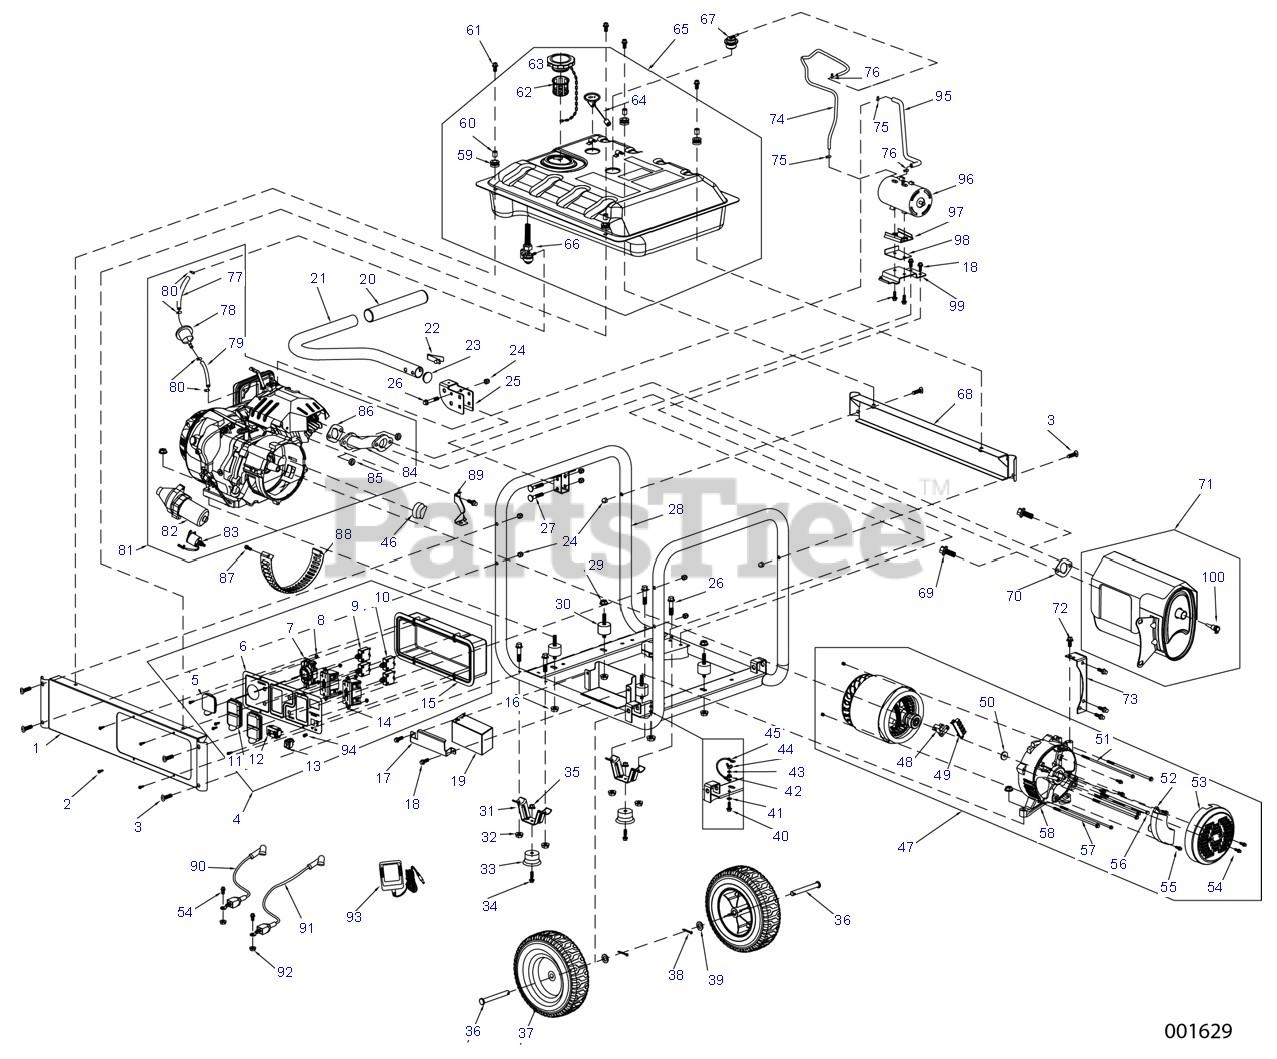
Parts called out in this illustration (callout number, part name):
1	FRAME RAIL
2	PAN SCREW (M5X16)
3	CURVED HEAD BOLT (M8X40)
4	CONTROL PANEL ASSEMBLY
5	OUTLET COVER
6	CONTROL PANEL FACE PLATE
7	OUTLET 30A 120/250V
9	30A CIRCUIT BREAKER
10	20A CIRCUIT BREAKER
11	OUTLET COVER
12	HOUR METER
13	ENGINE SWITCH
14	OUTLET 20A 120V GFCI
15	BACK PANEL COVER
17	BATTERY BRACKET COVER
18	BOLT(M6X12)
19	BATTERY
20	HANDLE GRIP
22	SNAP BUTTON
24	LOCKING CAP NUT (M8)
25	HANDLE BRACKET
26	BOLT (M8X45)
27	CARRIAGE HEAD BOLT (M8X46)
29	NUT (M10)
30	RUBBER VIBRATION MOUNT
31	BENT FRAME FOOT
32	NUT (M8)
33	RUBBER FOOT
34	BOLT (M6X28)
35	NUT (M6)
36	AXLE PIN
37	COMPLETE WHEEL
38	COTTER PIN
39	FLAT WASHER
40	BOLT (M6X20)
41	SPECIAL LOCK WASHER
43	FLAT WASHER (6X0.8)
44	NUT (M6)
45	GROUND WIRE ASSEMBLY
47	ALTERNATOR ASSEMBLY
48	ALTERNATOR BRUSH
49	WIRE CONNECTOR TERMINAL
50	FLAT WASHER (M10X4)
51	STATOR BOLT (M5X232)
52	AUTOMATIC VOLTAGE REGULATOR
53	GENERATOR END COVER
54	BOLT (M5X12)
55	BOLT (M5X16)
56	ROTOR BOLT (M10X285)
57	STATOR BOLT (M6X193)
58	BEARING CARRIER HOUSING
59	RUBBER MOUNT
60	ANTI-CRUSH INSERT
61	BOLT (M8X20)
62	GAS TANK FUEL FILTER
63	FUEL CAP
64	FUEL METER
65	FUEL TANK 8 GALLON
66	FUEL SHUTOFF VALVE
67	ROLL OVER VALVE
68	BACK FRAME RAIL
69	BOLT(M8X25)
70	MUFFLER EXHAUST GASKET
71	MUFFLER
72	BOLT (M8X16)
73	MUFFLER BRACKET
74	PREFORMED HOSE
75	HOSE CLAMP
76	HOSE CLAMP
77	FUEL HOSE (8X55)
78	FUEL FILTER
79	FUEL HOSE (8X80)
80	HOSE CLAMP
81	ENGINE 420CC
82	STARTER MOTOR
83	CONTACTOR ASSEMBLY
84	EXHAUST MANIFOLD
86	EXHAUST GASKET
87	BOLT (M5X10)
88	DUST COVER SHROUD
89	AIR CLEANER BRACKET
90	POSITIVE RED BATTERY CABLE
91	NEGATIVE GREEN BATTERY CABLE
93	BATTERY CHARGER
94	12VDC BATTERY CHARGER INPUT JACK
95	CARBON CANISTER BREATHER TUBE
96	CARBON CANISTER
97	CARBON CANISTER BRACKET
98	GUIDE PLATE BRACKET
99	CARBON CANISTER BRACKET
100	SPARK ARRESTOR
